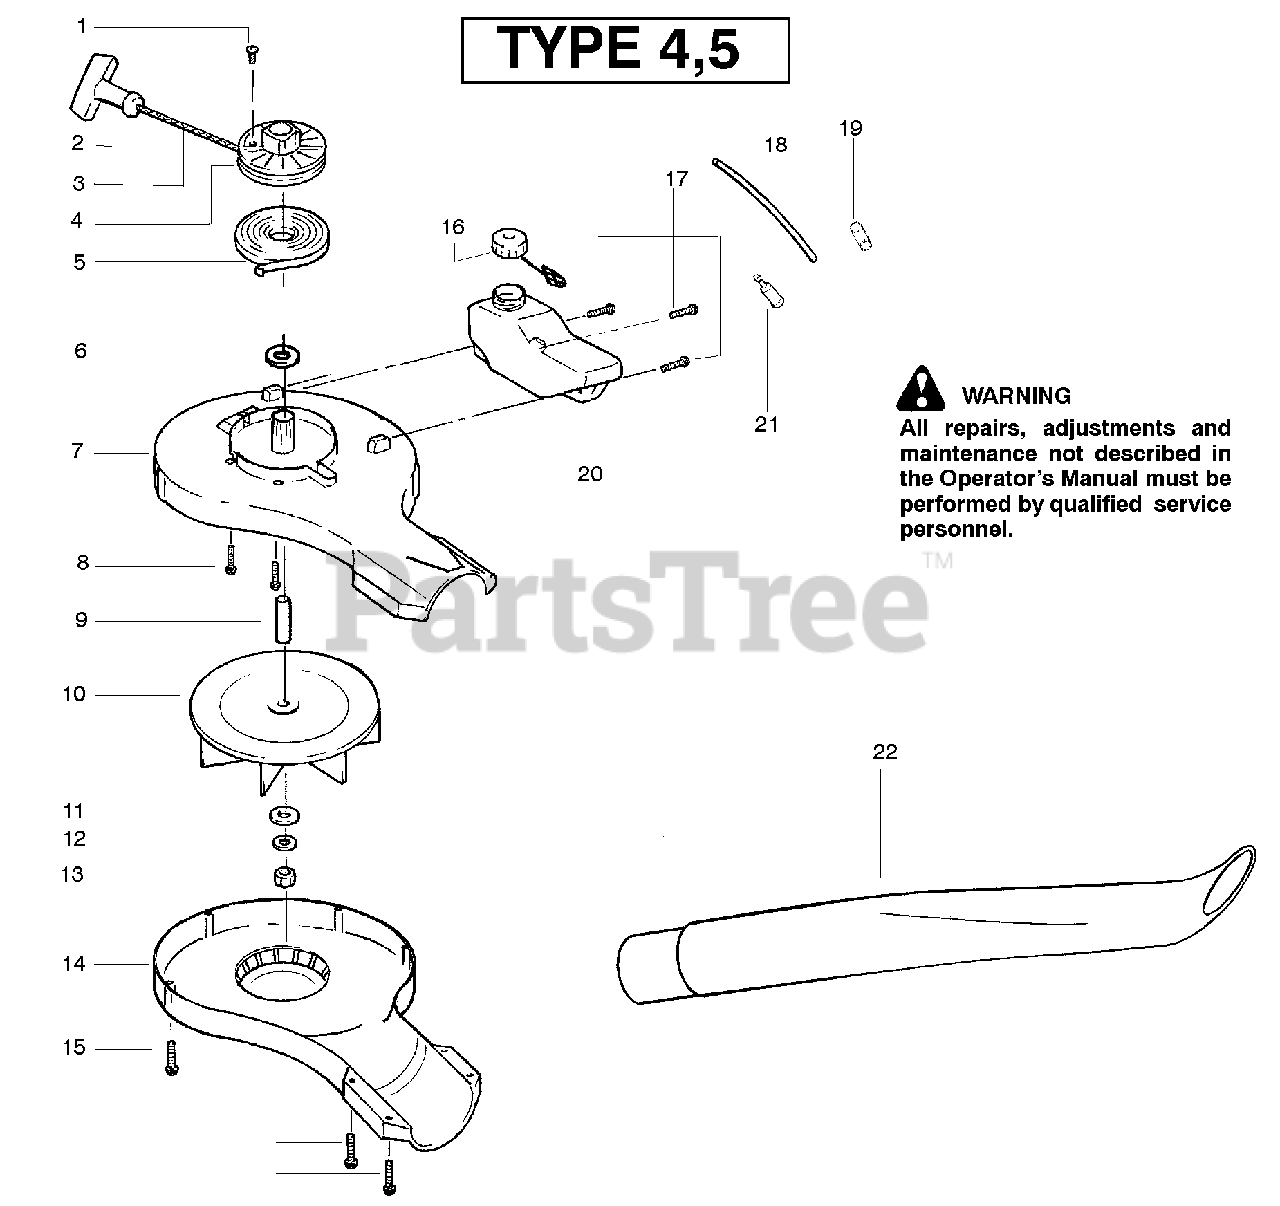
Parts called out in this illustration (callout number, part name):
2	Handle-Starter
4	Kit-Starter Pulley
5	Spring-Starter
7	Housing-Impeller (Upper)
9	Spacer-Flywheel
10	Assy-Impeller
14	Assy-Impeller Housing (Lower)
16	Assy-Fuel Cap
18	Kit-Fuel Line
19	Grommet-Fuel Line
20	Assy-Fuel Tank
21	Fuel Pick-up Ass'y.
